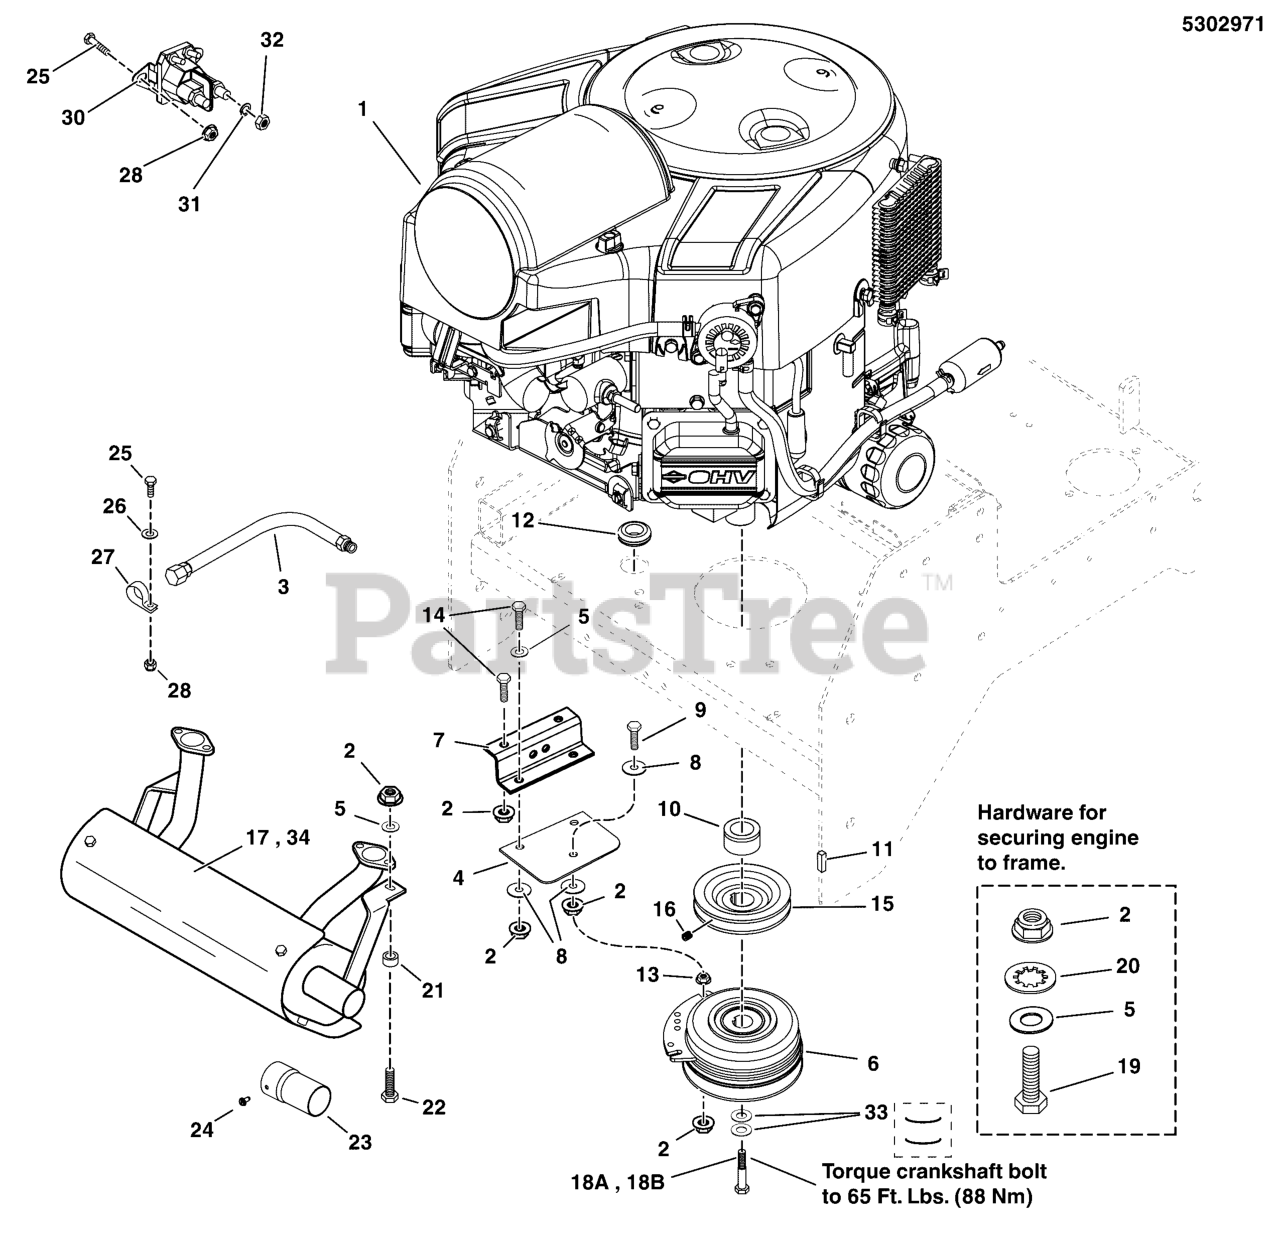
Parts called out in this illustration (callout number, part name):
1	* ENGINE, B&S, COMM TURF
2	NUT, 5/16-18 HEX NYLOCK FLANGE
3	HOSE, OIL DRAIN
4	CLUTCH ANCHOR PAD
5	WASHER, 5/16" SAE
6	** CLUTCH, 5218-134, WARNER
7	ANCHOR, CLUTCH - BLK
8	WASHER, .34 X 1.25 X 10 GA
9	BOLT, 5/16-18 X 2-1/4 TFL, GD5 YZ
10	SPACER, 1.13 X 1.75 X 1.25
11	KEY, 1/4 SQ X 1-1/4
12	GROMMET, 7/8
13	NUT, 5/16-18 HEX SERRATED FLANGE (SMALL)
14	BOLT, 5/16-18 X 1 GD5 YZ
15	PULLEY, 4.75 OD X 1-1/8 BORE, BC-48
16	SET SCREW, 5/16-18 X 3/8, KNURL
17	MUFFLER, B&S-ELS
19	BOLT, 5/16-18 X 1-3/4 GD5 YZ
20	WASHER, 5/16 INT. TOOTH LOCK
21	SPACER, .39 X 1.00 X .80, CZ
22	BOLT, 5/16-18 X 1-3/4 GD5 YZ
23	EXTENSION, TAILPIPE, 3" - BLACK
24	SCREW
25	BOLT, 1/4-20 X 3/4 GD5 YZ
26	WASHER, 1/4 SAE
27	CLAMP, VINYL INSULATED
28	NUT, 1/4-20 HEX NYLOCK FLANGE
30	SOLENOID-4 POLE 12 VOLT DC (TROMBETTA)
31	WASHER, Light Lock, 5/16
32	NUT, Hex Jam, 5/16-24
33	BELLEVILLE WASHER 1.1875 X .442 X .089
34	MUFFLER, RIGHT OUTLET ASSY
